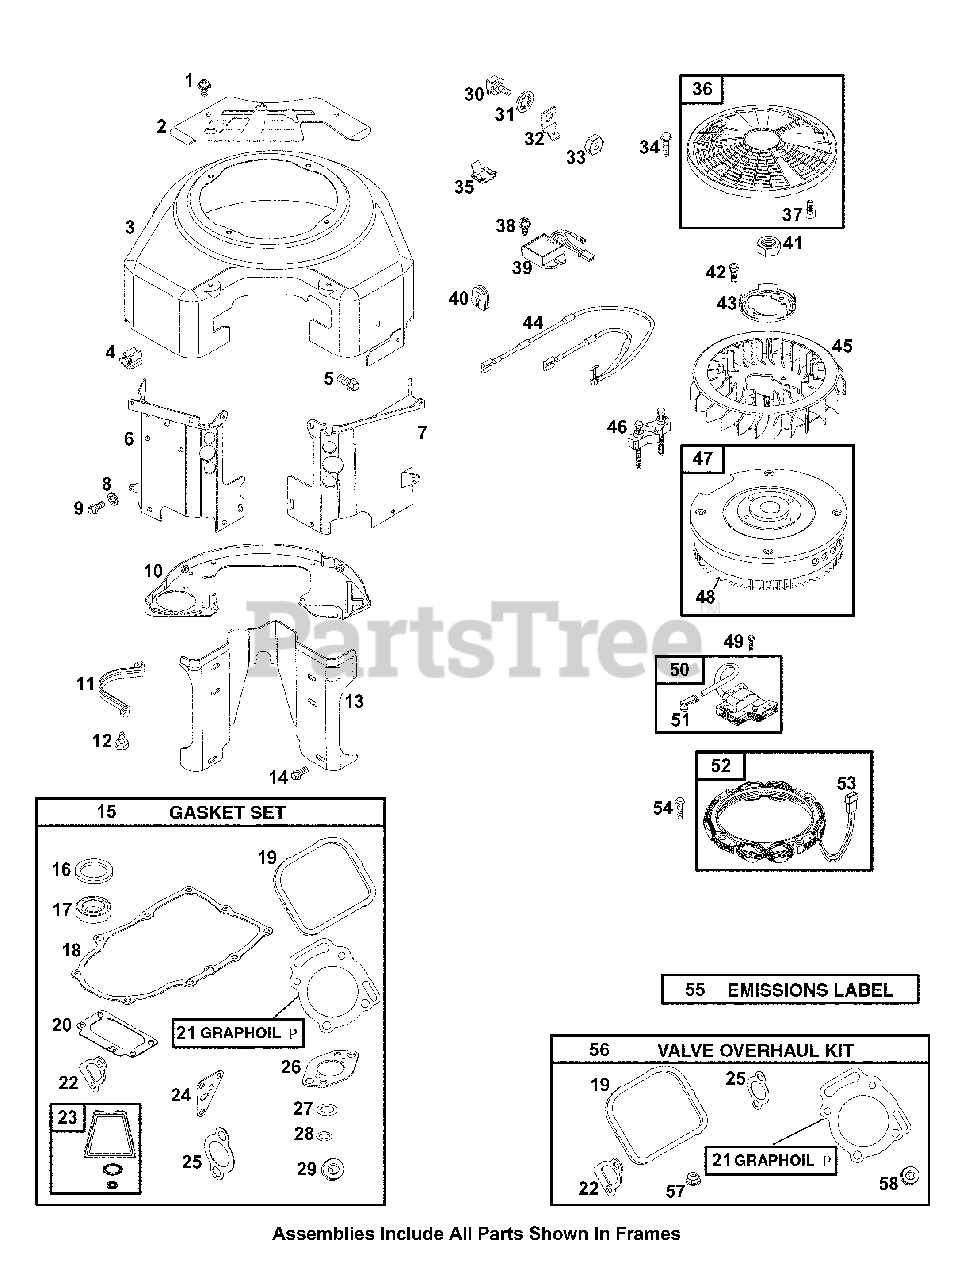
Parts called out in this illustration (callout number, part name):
1	Screw (Carburetor Cover)
2	Carburetor Cover
3	Blower Housing (Red)
5	Screw (Housing Blower)
6	Air Guide Cover (Cylinder #1)
7	Cylinder Cover (Cylinder #2)
8	Washer (Air Guide Cover)
9	Screw (Air Guide Cover)
10	Back Plate
11	Starter Drive Cover
12	Screw (Starter Drive Cover)
13	Air Guide Cover
14	Screw (Air Guide Cover)
15	Gasket Kit
16	Oil Seal
17	Oil Seal
18	Crankcase Gasket
19	Rocker Cover Gasket
20	Air Cleaner Gasket
21	Cylinder Head Gasket
22	Intake Gasket
23	Breather Gasket
24	Oil Adapter Gasket
25	Exhaust Gasket
26	Intake Gasket
27	O-Ring Seal
28	O-Ring Seal (Oil Pump)
29	Sealing Washer (Carburetor Plug)
31	Washer (Ground Terminal)
32	Ground Terminal
33	Nut (Ground Terminal)
34	Screw (Rotating Screen)
35	Debris Clip
36	Rotating Screen
38	Screw (Regulator)
39	Regulator
41	Nut (Flywheel)
42	Screw (Fan Retainer)
43	Fan Retainer
44	Wire Assembly
45	Flywheel Fan
46	Flywheel Puller
49	Screw (Magneto Armature)
50	Magneto Armature
51	Cable Terminal
52	Alternator
53	Alternator Wire
54	Screw (Alternator)
55	Emissions Label Kit
56	Valve Overhaul Kit
57	Nut (Rocker Cover)
58	Sealing Washer
